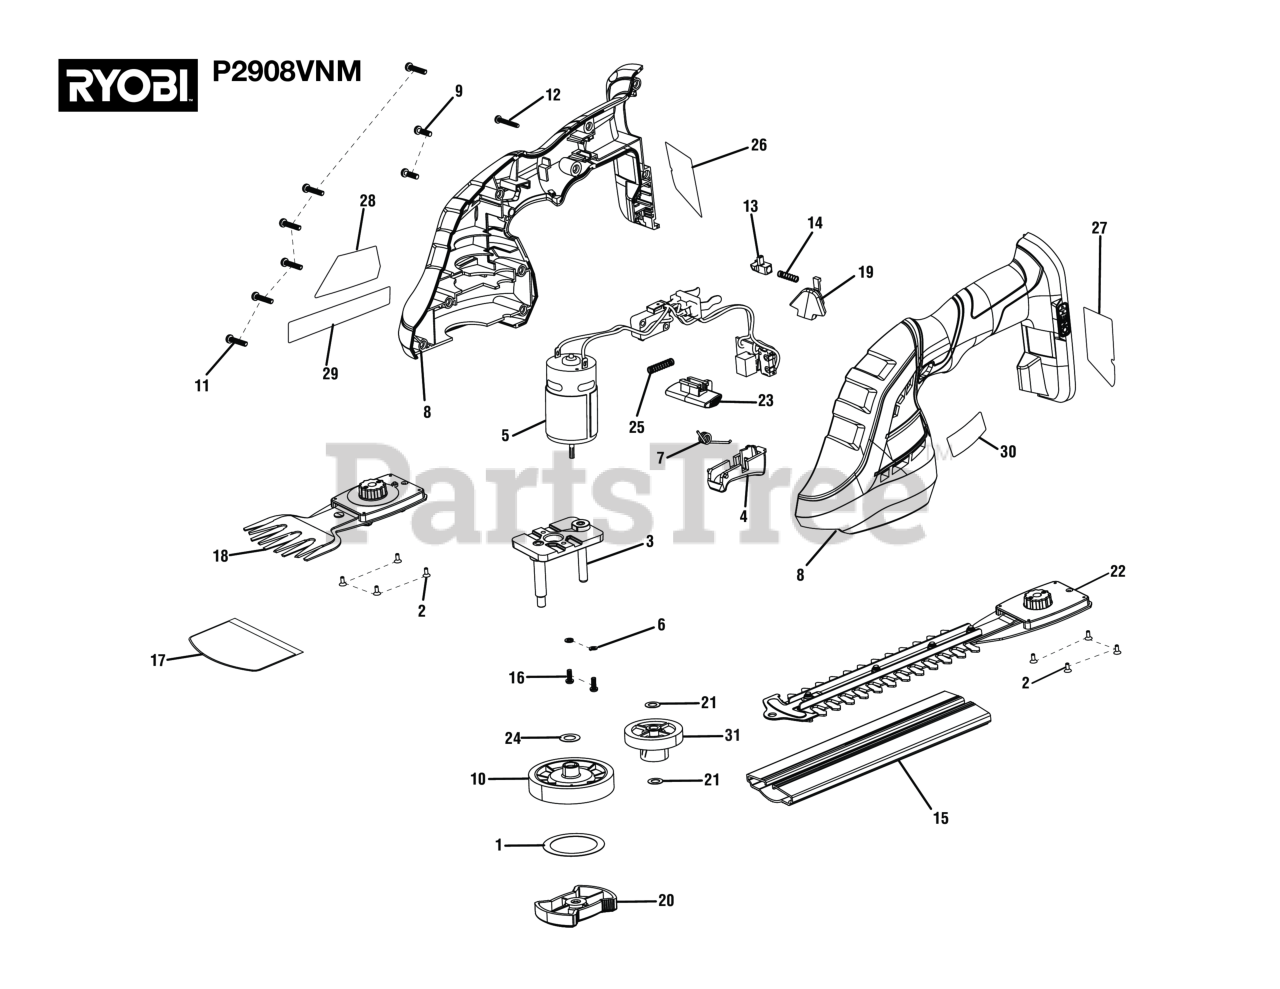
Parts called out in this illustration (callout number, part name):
2	Screw (M3 x 8.5 mm, Flat Hd.)
3	Motor Mount Assembly
5	Motor, Circuit Board, and Switch Assembly
6	Washer (OD5.7 x ID3.1 x 0.8t)
7	Trigger Spring
8	Housing Assembly (Inc. Key Nos. 26-30)
9	Screw (M3.5 x 12 mm, Pan Hd.)
11	Screw, M36.5x16mm, Pan. Head, Steel
12	Screw (M3 x 20 mm, Pan Hd.)
13	Slider for Switch
14	Compression Spring (Internal Tooth)
16	Screw, M3x8mm, Steel
18	Grass Shear Blade Assembly
19	Rubber Socket Port Cover
20	Knob Assembly
21	Washer (M6, ID6.2 x 11OD x 0.3t)
22	Hedge Trimmer Blade Assembly
23	Lock-Off Button
24	Washer, OD15xID8.4xT0.3
25	Compression Spring
26	Data Label
28	Danger Label
29	Icon Label
30	Logo Label
31	Step Gear
